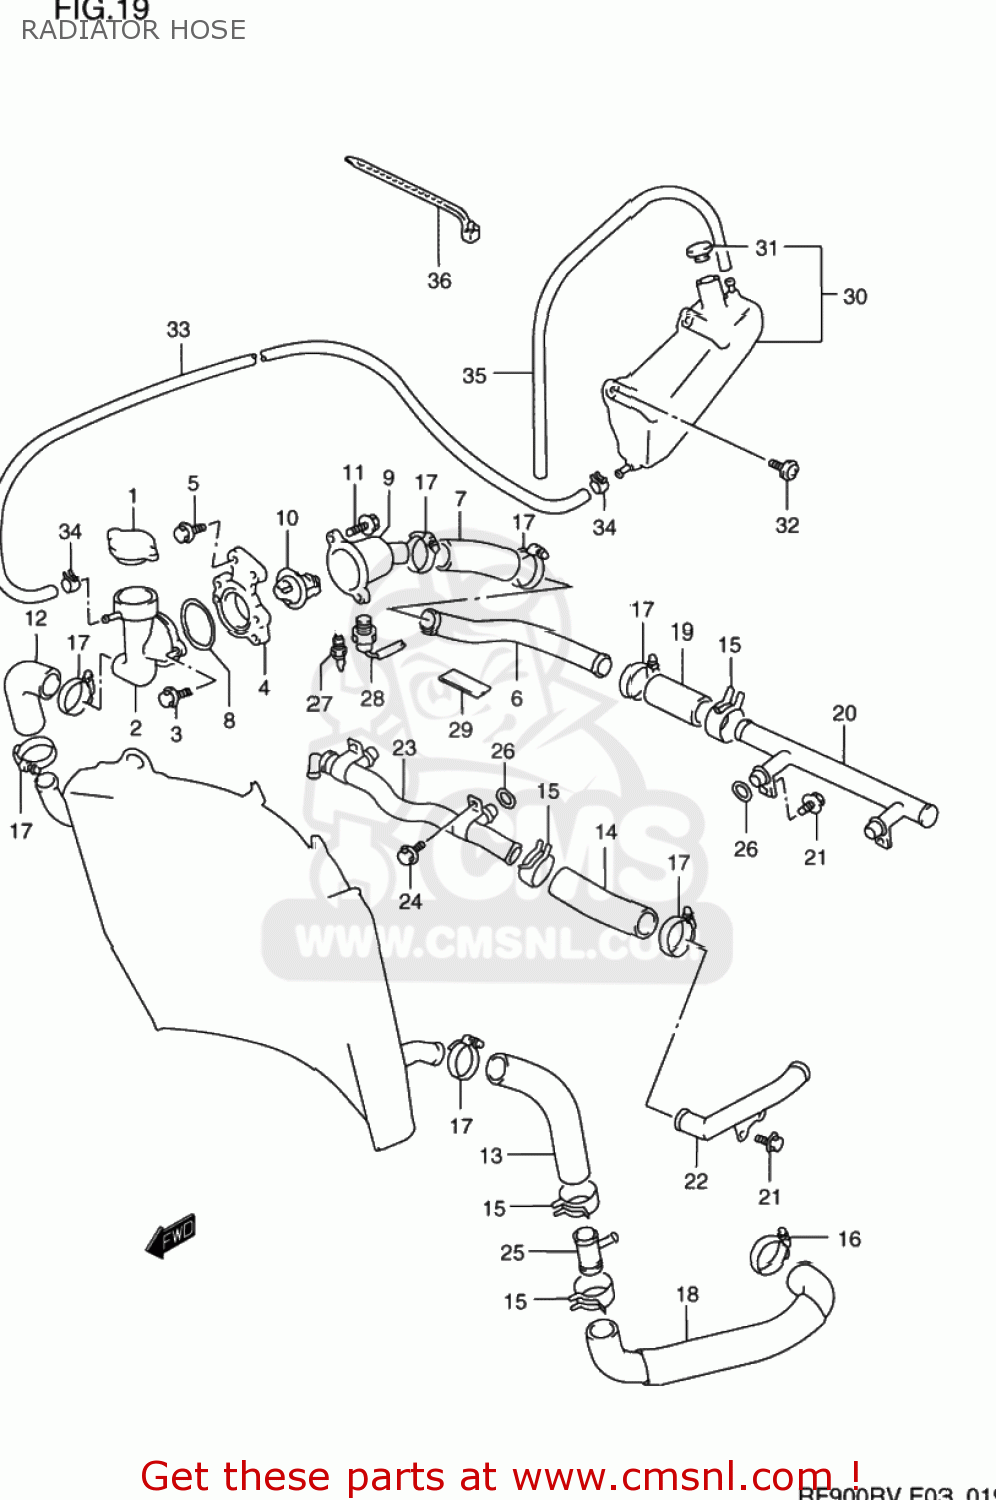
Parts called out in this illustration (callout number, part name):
1	CAP,RADIATOR
2	CONDUCTION,RADIATOR
3	BOLT
4	BRACKET,CONDUCTION
5	BOLT
6	PIPE,CONDUCTION INLET
7	HOSE,WATER
8	O RING(D:2.4,ID:43.2)
9	CONNECTOR,THERMOSTAT INLET
10	THERMOSTAT,WATER
11	BOLT
12	HOSE,RADIATOR INLET
13	HOSE,RADIATOR OUTLET
14	HOSE,WATER
15	CLAMP
16	CLAMP
17	CLAMP
18	HOSE,WATER PUMP INLET
19	HOSE,HEAD OUTLET
20	PIPE,HEAD OUTLET
21	BOLT
22	PIPE
23	PIPE COMP,CYLINDER INLET
24	BOLT
25	UNION,HOSE JOINT
26	O RING(D:3.2,ID:17.8)
27	GAUGE ASSY,WATER TEMP
28	SWITCH COMP,RADIATOR FAN
29	CUSHION(50X42X2.0)
30	TANK ASSEMBLY,RESERVOIR
31	CAP,RESERVOIR TANK
32	SCREW(6X20)
33	HOSE,RESERVOIR TANK
34	CLIP
35	HOSE,RESERVOIR TANK
36	CLAMP L:165
